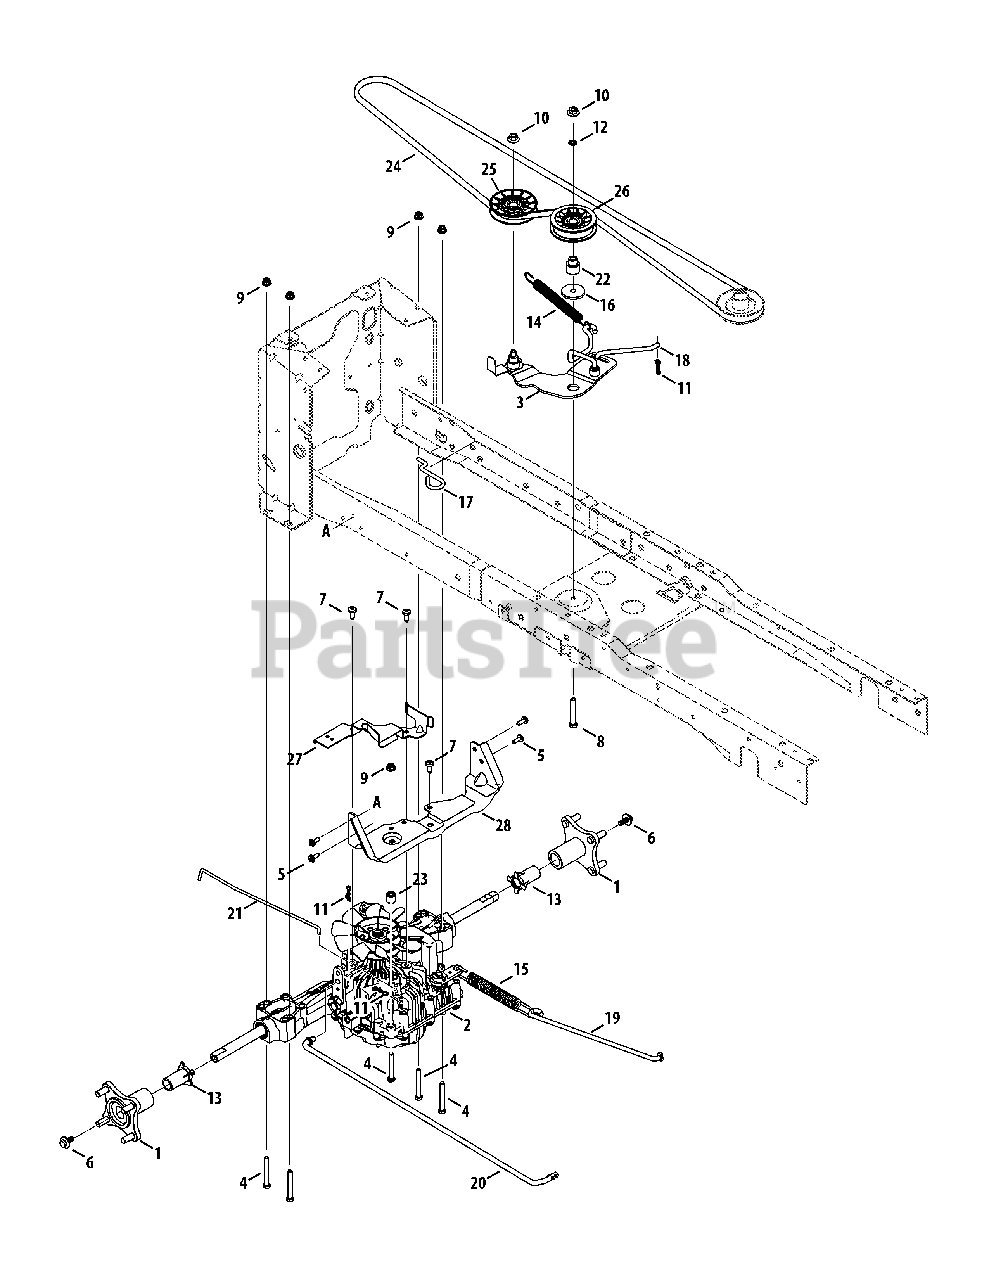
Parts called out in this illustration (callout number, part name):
1	Hub Assembly, Wheel
2	Transmission, Tuff Torq K46
3	Idler bracket Assembly
4	Hex Screw, 5/16-18, 2.50, Gr5, Std
5	Screw, M6-1 x .625
6	Screw, 5/16-24 x .850
7	Screw, Self-tapping, 5/16-18, 0.750
8	Hex Screw, 3/8-16, 2.25, Gr5
9	Nut, Flange Lock, 5/16-18, Nylon
10	Flange Lock Nut, 3/8-16
11	Pin, Cotter, Bow-Tie 72
12	Speed Nut
13	Sleeve, .765 ID x 1.575
14	Spring, Extension, .790 Dia x 8.41
15	Spring, Extension, .90 Dia x 8.14
16	Shoulder Spacer, .884 x .190
17	Deck Spring Rod
18	Idler Link
19	Rod, Brake, Tuff Torq
20	Rod, Control, Tuff Torq
21	Rod, Transmission, Bypass
22	Shoulder Spacer
23	Spacer, .34 x .75 x .63
24	Belt, V-Type
25	Idler Pulley, 3.56 OD
26	Idler Pulley, 3.00 OD
27	Belt Keeper Bracket
28	Transmission Bracket
